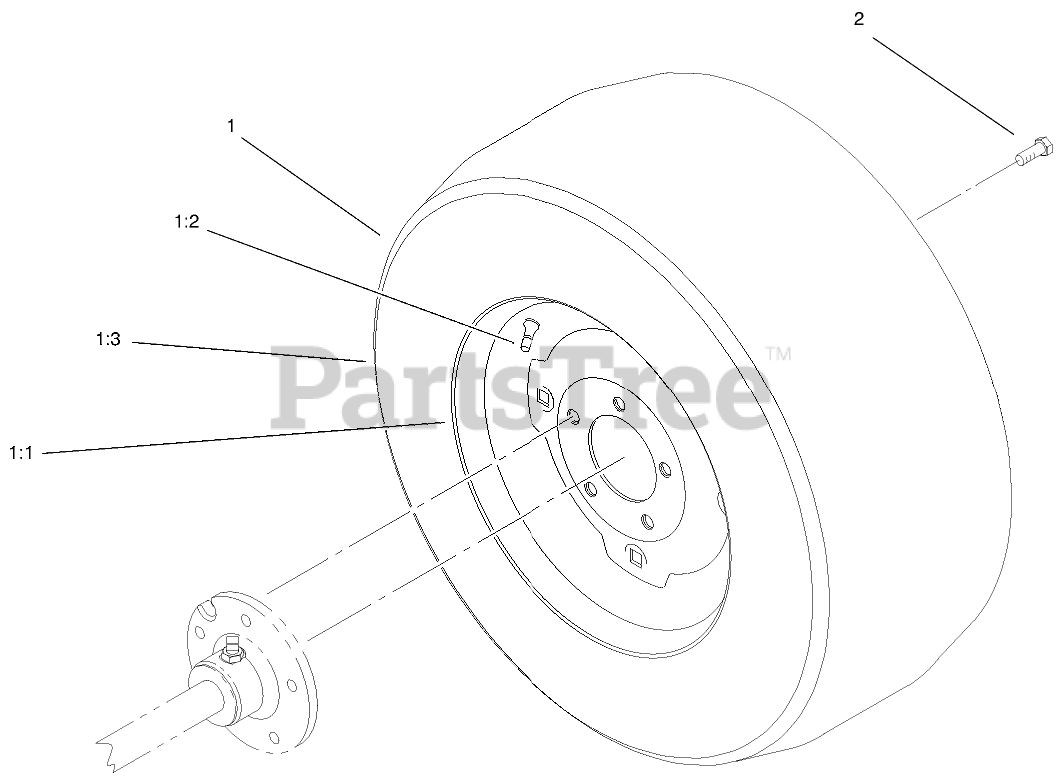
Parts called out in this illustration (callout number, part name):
1	Rear Wheel & Tire ASM (Only On: 73545)
1	Rear Wheel & Tire ASM (Only On: 73546)
1:1	Tire (Only On: 73545)
1:1	Tire (Only On: 73546)
1:2	VALVE
1:3	RIM ASM
2	BOLT-LUG
